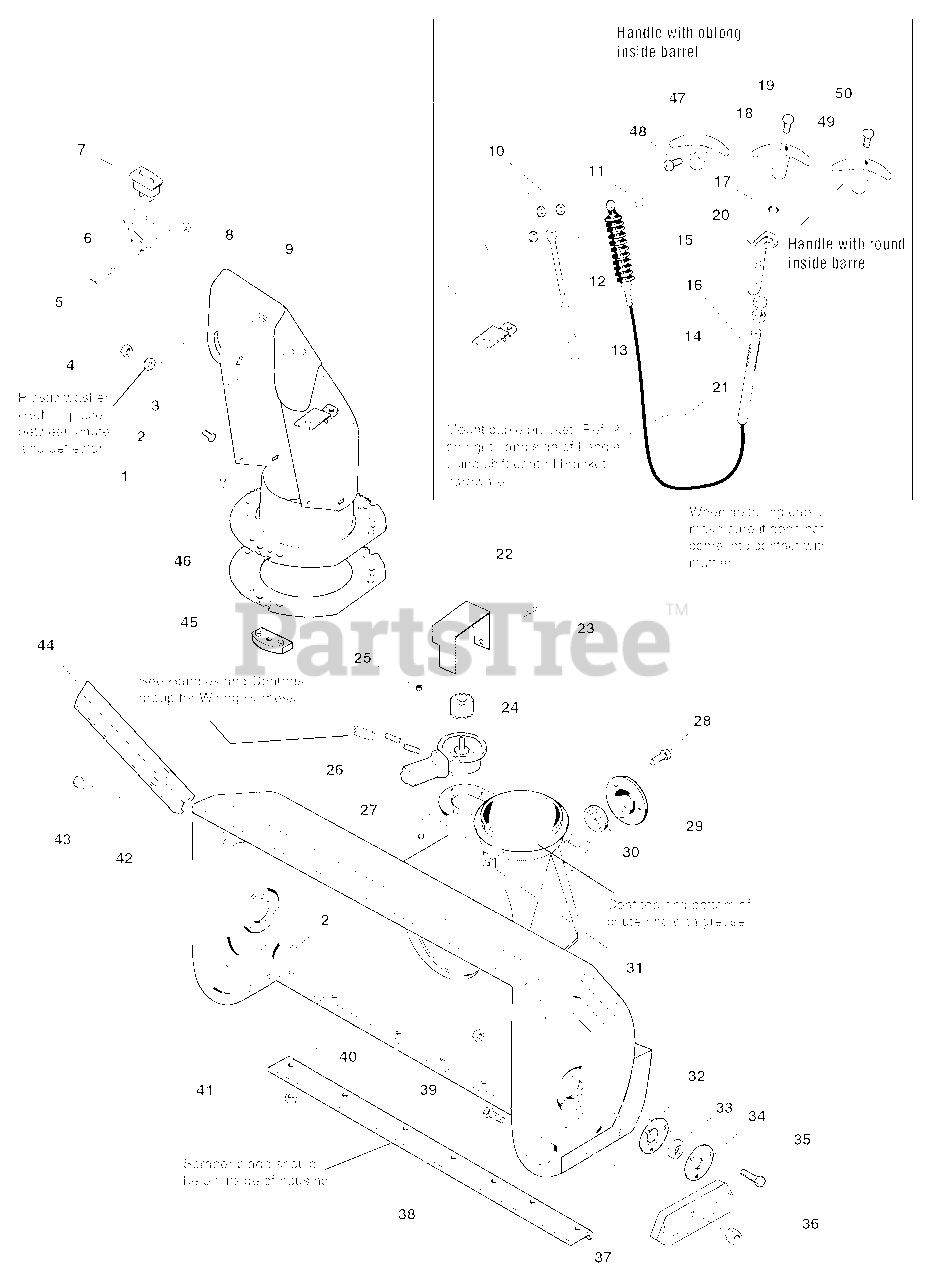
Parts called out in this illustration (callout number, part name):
1	SCREW, Hex Washer Head Pastite, 10-14 x 5/8
2	CARRIAGE BOLT, 5/16-18 x 3/4 G5
3	WASHER, Special, 97/250ID x 1-3/25OD x 3/100 Thick
4	NUT, Hex Flange ESNA, 5/16-18
5	SCREW, Hex Whiz Lock, 1/4-20 x 3/4
6	BRACKET, Mounting Switch
7	SWITCH, Rocker Chute
8	NUT, Hex Nylon 10-24
9	CHUTE AND DEFLECTOR ASSEMBLY
10	SPACER, Heat Treated
11	NUT, Push Pal, 1/4" Diameter Stud Capped
12	ROD, 5/16" Diameter, Spring Guide
13	SPRING, Complete
14	CABLE AND KNOB ASSEMBLY, Chute (Includes Ref. No. 18, 19, 20, 21 & 22)
15	BOOT, Bellows
16	COLLET
17	SEAL, Rod
18	KNOB
19	SCREW, 8-32
20	SUPPORT, Cable
21	TIE, Self Locking
22	COVER, Pinion, 18GA
23	CAPSCREW, Hex Washer Head Taptite, 1/4-20 x 1/2
24	PINION, 1-3/20 LG
25	NUT, Hex KEPS, #10-24
26	MOTOR, Electric
27	CAPSCREW, Hex Washer, #10 x 1-1/4
28	CAPSCREW, Hex Head Whiz Lock, 5/16-18 x 3/4
29	RETAINER, Bearing
30	BEARING, Ball
31	NUT, Retainer Speed, 5/16-18
32	FLANGE, Bearing, w/Fitting
33	BEARING, Cartridge
34	FLANGE, Bearing, 3/8" Deep
35	CAPSCREW, Hex head, 5/16-18 x 5/8
36	NUT, Hex Flange, 3/8-16 ESNA
37	SKID SHOE
38	BLADE, Scraper, 35-3/4 for 38"
39	BOLT, Carriage, 3/8-16 X 1
40	NUT, Hex Flange Whiz Lock, 5/16-18
41	NUT, Flange Lock, 5/16-18
42	HOUSING AND IMPELLER ASSEMBLY, 38"
43	CAPSCREW, Hex Washer Head Taptite, 5/16-18 x 3/4 G5
44	CUTTER, Drift, Red
45	HOLD DOWN, Chute
46	GEAR, Chute
47	HANDLE "T"
48	SCREW, Set, Hex #10-24 x 3/8
49	HANDLE "T"
50	SCREW, Round Head
